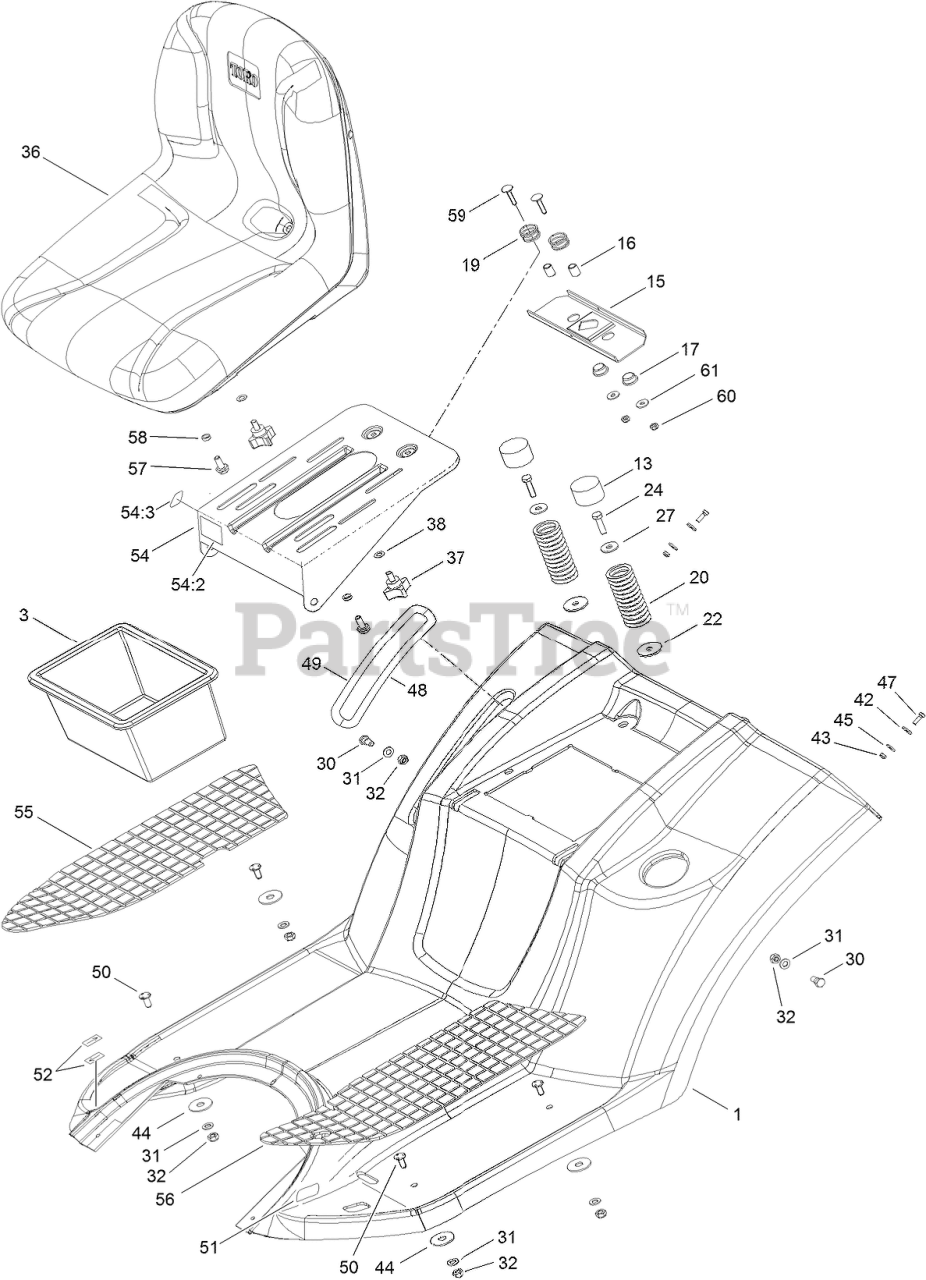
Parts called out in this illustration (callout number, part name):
1	FENDER-REAR
3	Box-Battery
13	CAP-HUB
15	BRACKET
16	SPACER-SPLIT
17	BUSHING
19	SEAT-SPRING
20	SPRING-SEAT
22	WASHER
24	SCREW-HH
27	WASHER-PLAIN
30	SCREW-SUPPORT, SEAT
31	WASHER-PLAIN
32	NUT-LOCK, NI
37	KNOB-ADJUST
38	WASHER-SPRING
42	WASHER-FLAT
43	NUT-LOCK
44	WASHER-RUBBER
45	WASHER-RUBBER
48	DECAL-MOWING LIFT, LEFT
49	DECAL-MOWING LIFT, RIGHT
50	SCREW-HSFH
51	DECAL-BRAKE, PARKING
52	DECAL-TRAVEL
54	BRACKET-SUPPORT, SEAT
54:2	DECAL-DANGER
54:3	DECAL-SWITCH
55	MAT-FOOT, RH
56	MAT-FOOT, LH
57	SCREW-HHF
58	SPACER
59	SCREW-CARR
60	NUT-LOCK
61	WASHER-FLAT
